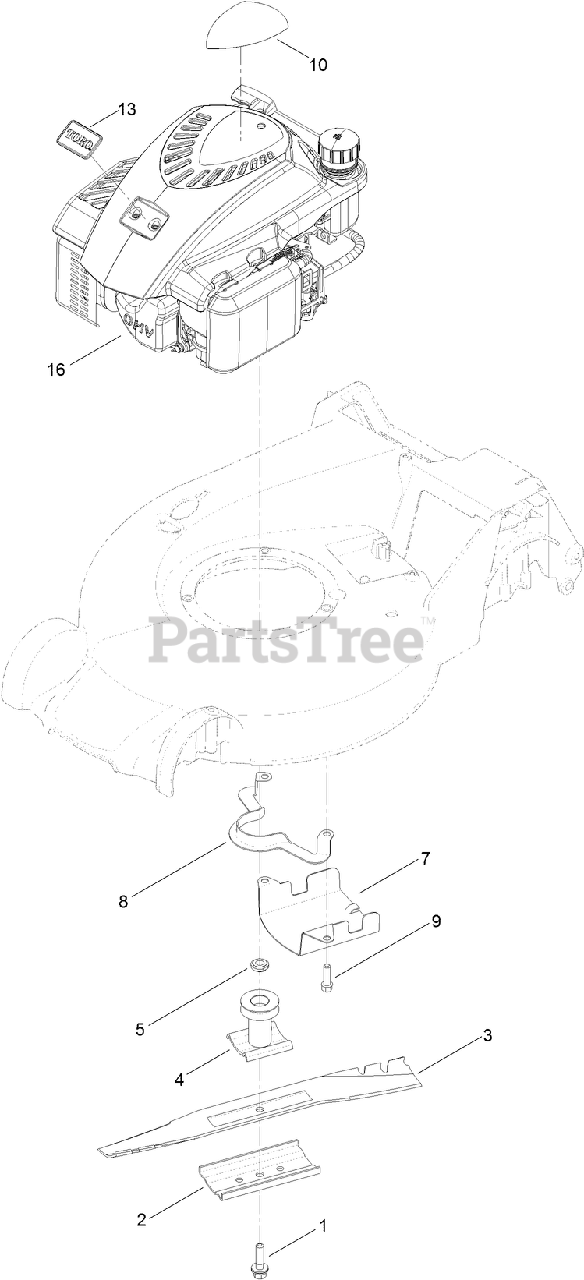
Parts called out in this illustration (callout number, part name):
1	BOLT-BLADE
2	SUPPORT-BLADE
4	DRIVER-BLADE
5	SPACER-DRIVER
7	SHIELD-GRASS
8	GUIDE-BELT
10	DECAL-SHROUD
13	PLATE-LOGO
16	ENGINE-1P65FC
